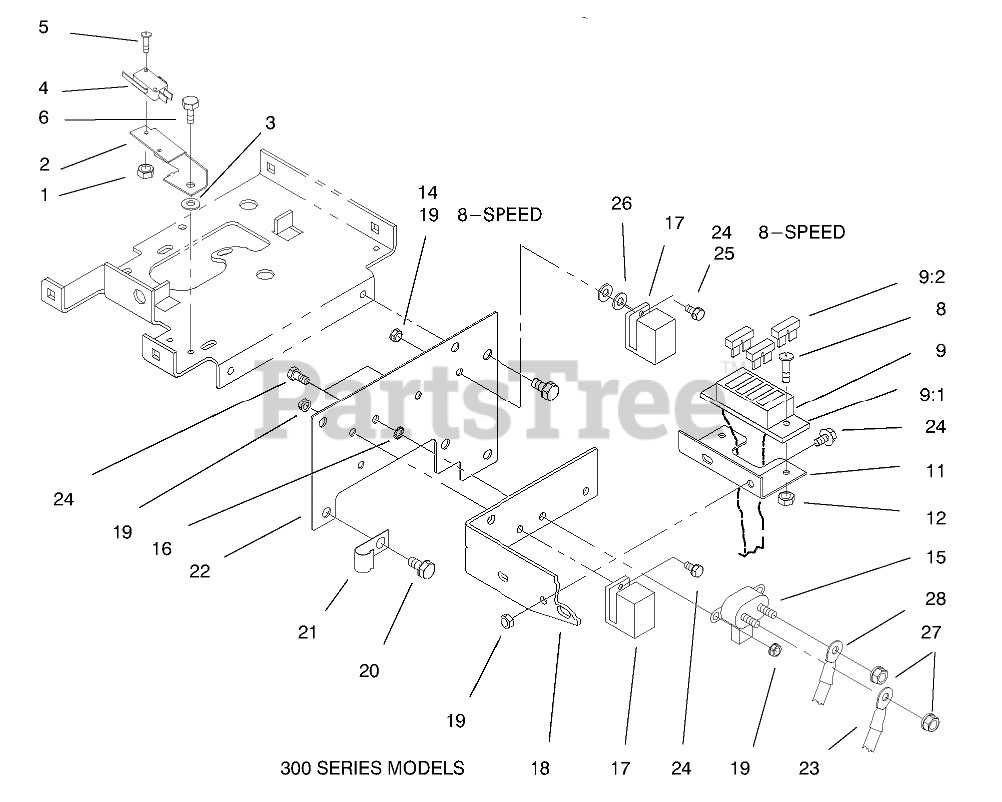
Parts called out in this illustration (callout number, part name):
1	NUT-HEX
2	BRACKET-SWITCH
3	WASHER-LOCK, INTERNAL
4	SWITCH
5	SCREW-PHL 4-40X1 1/4
6	SCREW-HWH
8	SCREW-PAN
9	WIRING-HARNESS & DIA
9:1	FUSE-HOLDER 4 WAY
9:2	FUSE-BLADE, 15 AMP
9:3	FUSE-BLADE, 25 AMP
9:4	FUSE-30 AMP
11	FUSE HOLDER
12	Nut
14	NUT-LOCK, NI
15	Solenoid
16	WASHER-LOCK/EXT
17	RELAY
18	BRACKET-BELT (BLACK)
19	NUT-LOCK, NI
20	Bolt
21	CLIP
22	PLATE-FRONT HOODS (BLACK)
23	ASSY WIRE
24	SCREW-HHF
25	SCREW-HHF
26	WASHER-FLAT
27	NUT-KEPS
28	CABLE-BLACK
